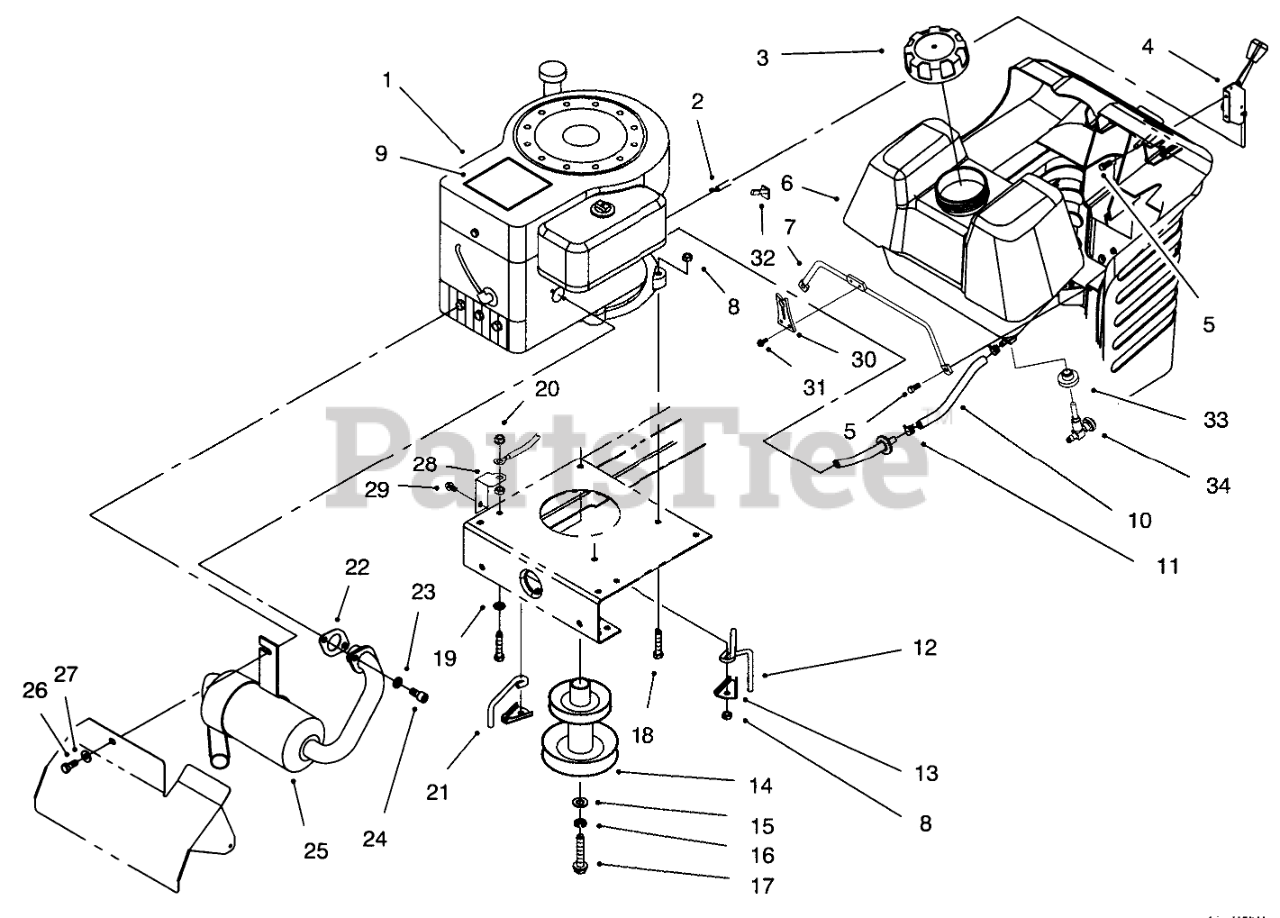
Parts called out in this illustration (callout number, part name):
1	Engine-12 H.P. (Model No. 71188 Only)
2	THROTTLE CABLE ASM
3	GAS CAP ASM
4	THROTTLE CONTROL ASM
5	SCREW-SPECIAL
6	GAS TANK ASM
7	RR OIL SEAL
8	NUT-LOCK, NI
9	DECAL - ENGINE
10	HOSE-FUEL
11	CLAMP-HOSE
12	GUIDE-BELT, LH
13	ANCHOR-GUIDE, BELT
14	PULLEY-ENGINE
15	WASHER-FLAT
16	WASHER-LOCK
17	SCREW-HH
18	SCREW-HH
19	WASHER-LOCK
20	NUT-KEPS
21	GUIDE-BELT, RH
22	GASKET-EXHAUST
23	WASHER-LOCK
24	SCREW-HSH
25	MUFFLER
26	SCREW-HH
27	WASHER-LOCK
28	BRACKET-GROUND
29	SCREW-HWH
30	LATCH-HOOD
31	SCREW-HWH
32	REDUCER-THROTTLE, RPM
33	BUSHING
34	VALVE-FUEL
